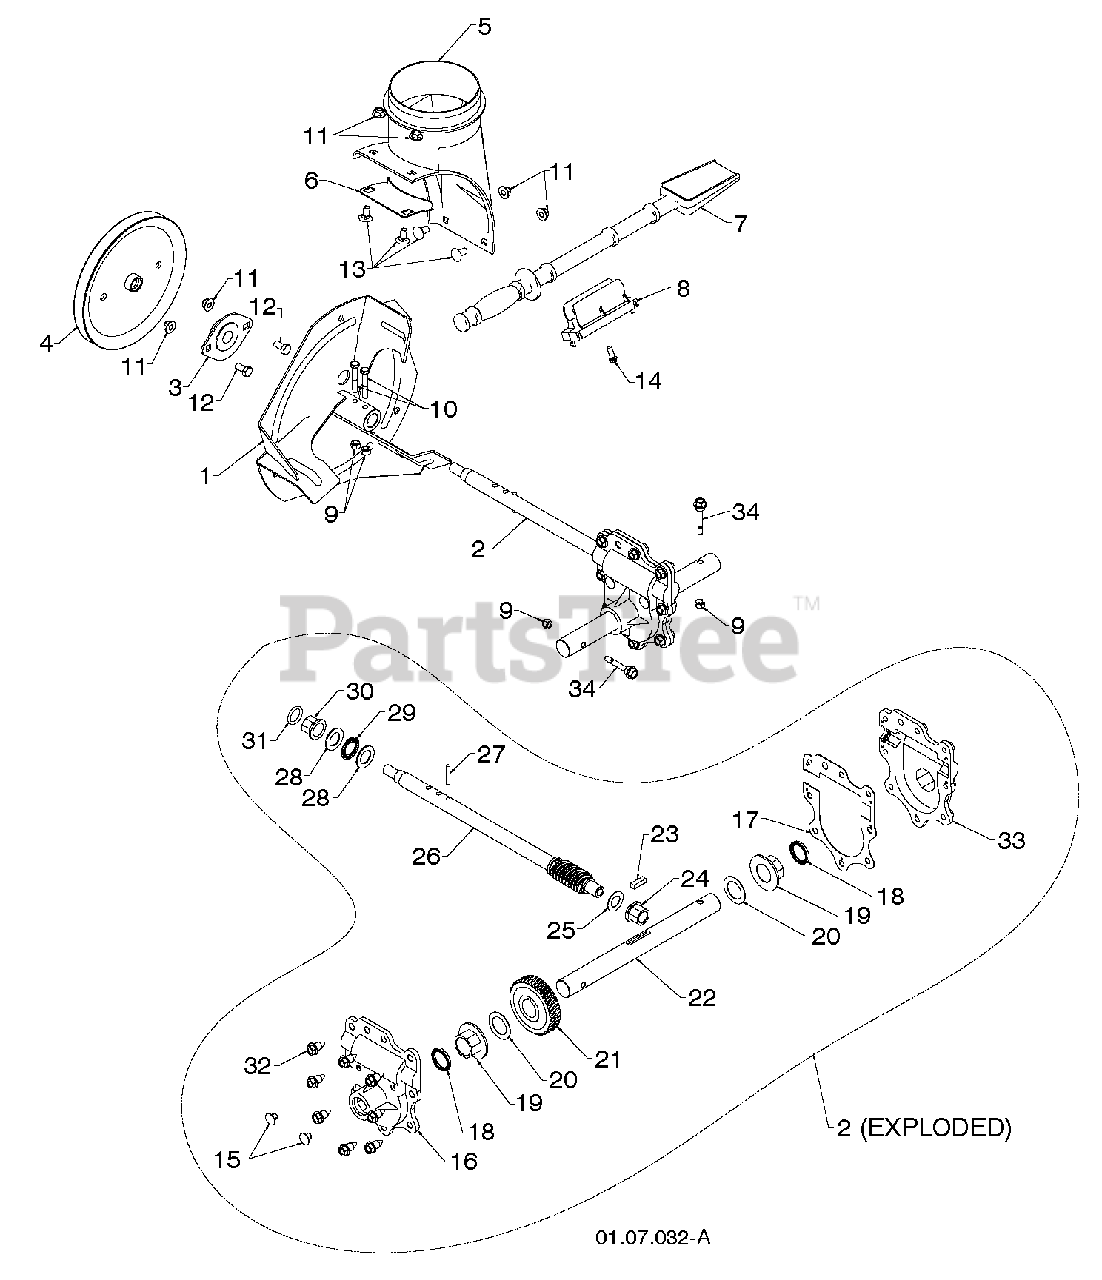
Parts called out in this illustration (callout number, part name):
1	IMPELLER ASSY
2	GEARBOX.AUGER.SCREW.ON.PULLEY
3	BEARING FLANGE
4	PULLEY.IMPELLER.7.5IN.SCREW.ON
5	BASE.DISCHARGE.CHUTE
6	BRACKET, CORNER DISCHARGE
7	CLEAN OUT TOOL
8	CLIP.CLEANOUT.TOOL
9	LOCKNUT.NYLOC.1/4-20
10	SCREW.HEX.HD1/4-20X
11	NUTNYLOK.FLRANGE.5/16-18
12	BOLT, HEX HEAD 5/16-18
13	BOLT.CARRIAGE.5/16-18X
14	SCREW.HWH.13-16-5.8.BZP
15	CASE PLUG
16	GEAR.BOX.COVER.RIGHT.SIDE
17	GASKET.GEAR.BOX
18	OIL SEAL
19	FLANGE BUSHING-1"
20	WASHER TRUST 1"
21	WORMGEAR.AUGER.SNOW
22	AUGER SHAFT
23	KEY, SQUARE 1/4 X .875
24	FLANGE BUSHING-5/8
25	WASHER, THRUST 5/8
26	SHAFT INOUT 1/2-20
27	PIN, ROLL 3/16 X 1-1/8
28	WASHER, THRUST 3/4
29	BEARING TRUST 3/4 NTA-1220
30	BUSHING, FLANGE 3/4
32	HEX SCREW-5/16 X 3/4
33	GEAR.BOX.COVER.LEFT.SIDE
34	BOLT.SHOULDER.SHEAR.1/4-20.
